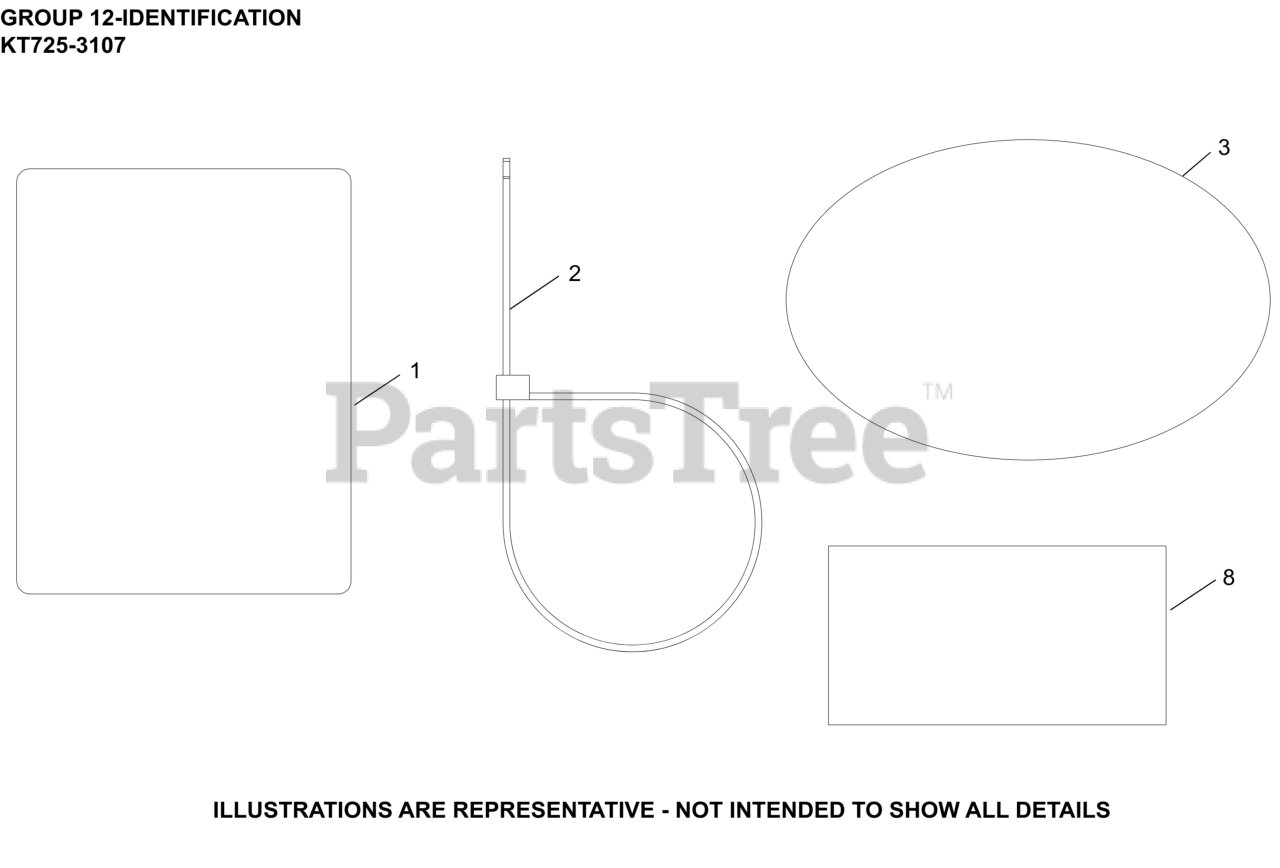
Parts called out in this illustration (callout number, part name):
1	LABEL, CLEAR LAMINATION
3	LABEL, 7000 SERIES KT725 (22 HP)
8	DECAL, USA
